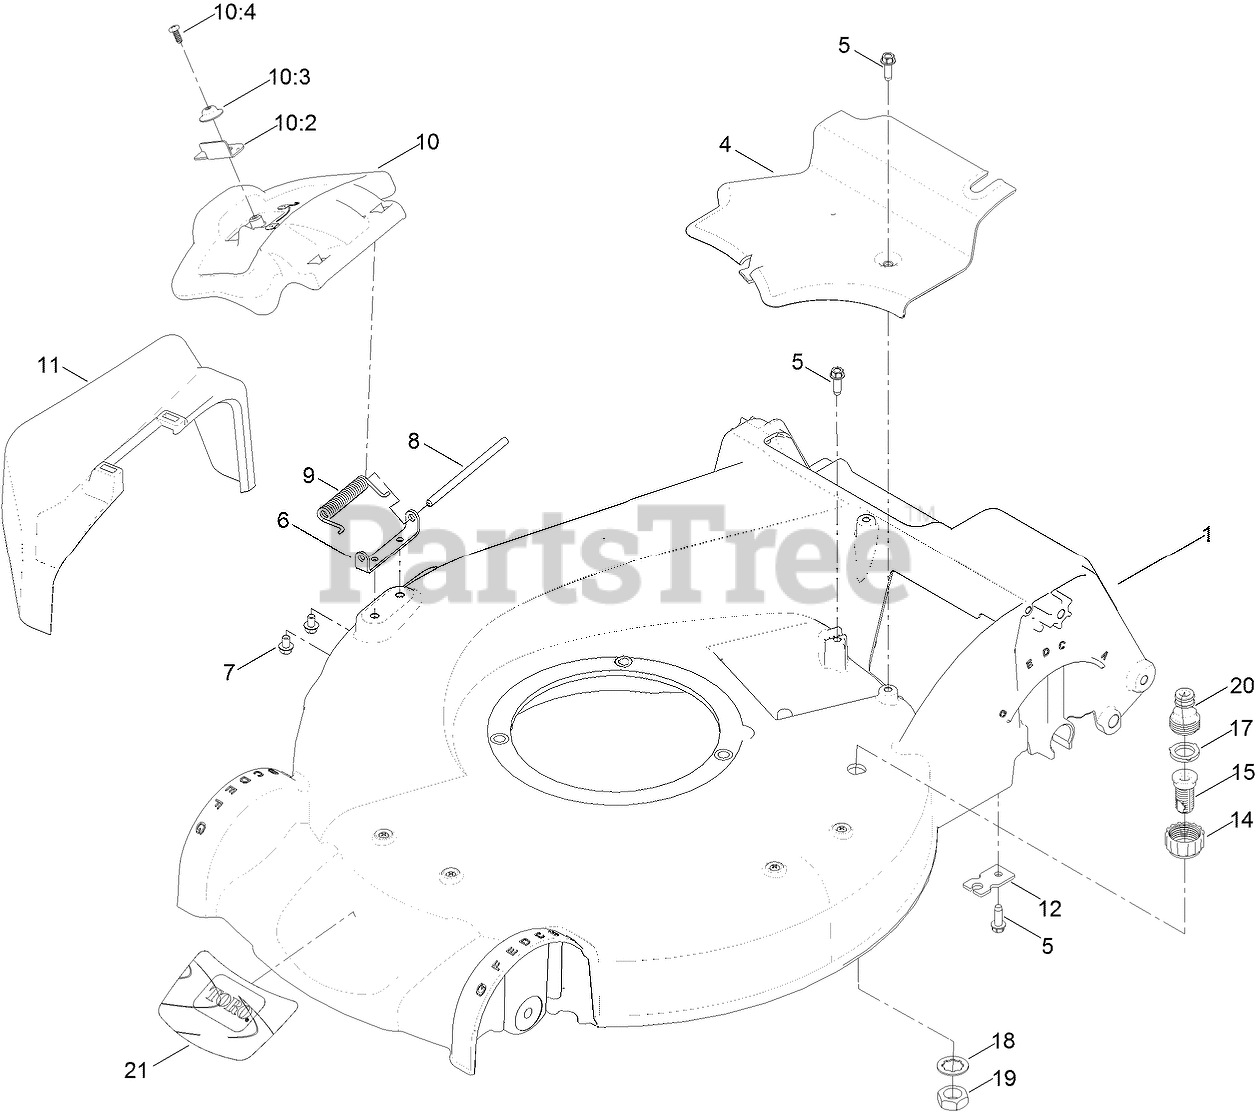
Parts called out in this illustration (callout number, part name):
1	HOUSING ASM
4	COVER-BELT
5	SCREW-HWHTF
6	BRACKET-COVER
7	SCREW-HWH
8	ROD-COVER
9	SPRING-TORSION
10	DISCHARGE DOOR ASM
10:2	LATCH-DOOR
10:3	CAP-DOOR
10:4	SCREW-PLASTITE
11	CHUTE-DISCHARGE, SIDE
12	BRACKET-CABLE, TRACTION
14	COUPLING-HOSE, WASHOUT PORT
15	PORT-WASHOUT
17	WASHER-SEAL, WASHOUT PORT
18	WASHER-TOOTH, INTERNAL
19	NUT-JAM
20	ADAPTER-CONNECT, QUICK
21	DECAL-DECK
